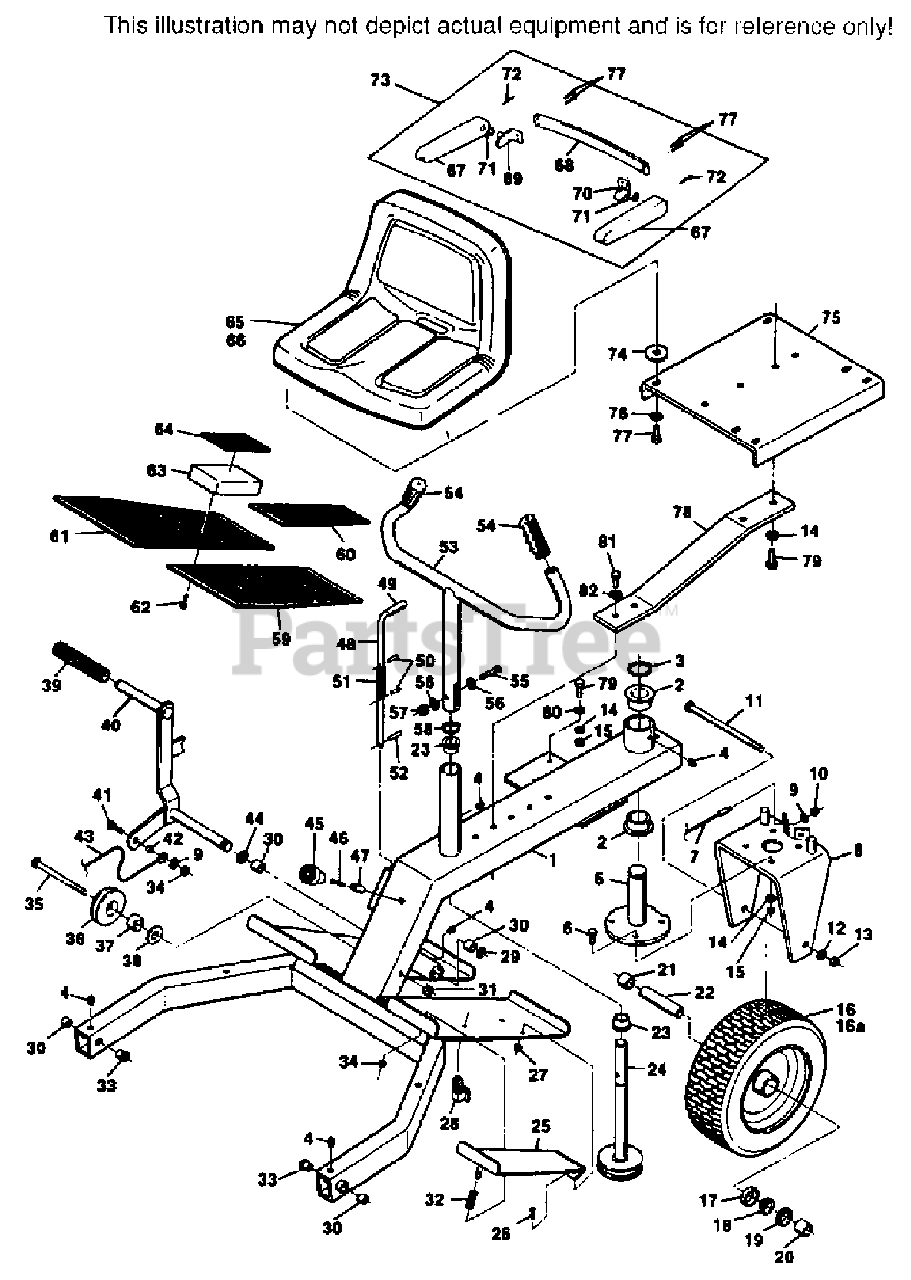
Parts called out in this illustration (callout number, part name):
1	STEERING FRAME WLD.
2	BRONZE BEARING
3	RETAINING RING, 1-1/8 EXT. BASIC
4	GREASE FITTING, 1/4-28 STR.
5	REAR WHEEL PIVOT WLD.
7	STEERING CABLE
8	REAR WHEEL YOKE WLD.
9	WASHER, 9/32 X 5/8 X 16 GA.
10	HEX LOCK NUT, 1/4-28
11	HEX HEAD BOLT, 5/8-11 X 9
16	CASTER WHEEL ASSEMBLY(INCL. 16A-19)
16A	RIM ONLY
17	BEARING CUP
18	BEARING CONE
19	GREASE SEAL
20	SPACER, SHORT
21	SPACER, LONG
22	REAR WHEEL SLEEVE
23	BRONZE BEARING
24	STEERING SHAFT WLD.
25	SAFETY PEDAL WLD.
27	HEX NUT, #10-32, ELASTIC STOP
28	FOOT SAFETY SWITCH(INCL. BOOT
29	RETAINING RING, 3/4 EXT. "E"
30	BRONZE BEARING
31	HEX NUT, 1/2-13, ELASTIC STOP
32	SPRING
33	BRONZE BEARING
35	HEX HD BOLT, 1/2-13 X 5-1/2
36	WINCH CABLE PULLEY(INCL. 37)
37	BRONZE BEARING
39	SLEEVE, FOOT PEDAL
40	FOOT PEDAL WLD.
42	SLEEVE
43	FOOT CABLE ASSEMBLY
44	WASHER, 49/64 X 1-1/4 X 16 GA.
45	BUMPER STOP COVER
47	BUMOPER STOP
48	PARKING BRAKE LEVER(INCL. 49)
49	GRIP
51	SPRING
53	STEERING HANDLE WLD.(INCL. 54)
54	GRIP
56	WASHER, 11/32 X 11/16 X 16 GA.
58	RETAINING RING, 7/8 EXT. BASIC
59	PAD - LH
60	PAD, SAFETY PEDAL
61	PAD - RH
65	SEAT ASSEMBLY
65A	ARM REST KIT
74	WASHER, 13/32 X 1-1/2 X 7 GA.
75	SEAT PLATE WLD.
76	LOCKWASHER, 5/16 SPRING
78	SEAT SUPPORT SPRING
80	WASHER, 13/32 X 13/16 X 16 GA.
82	LOCKWASHER, 7/16 SPRING
